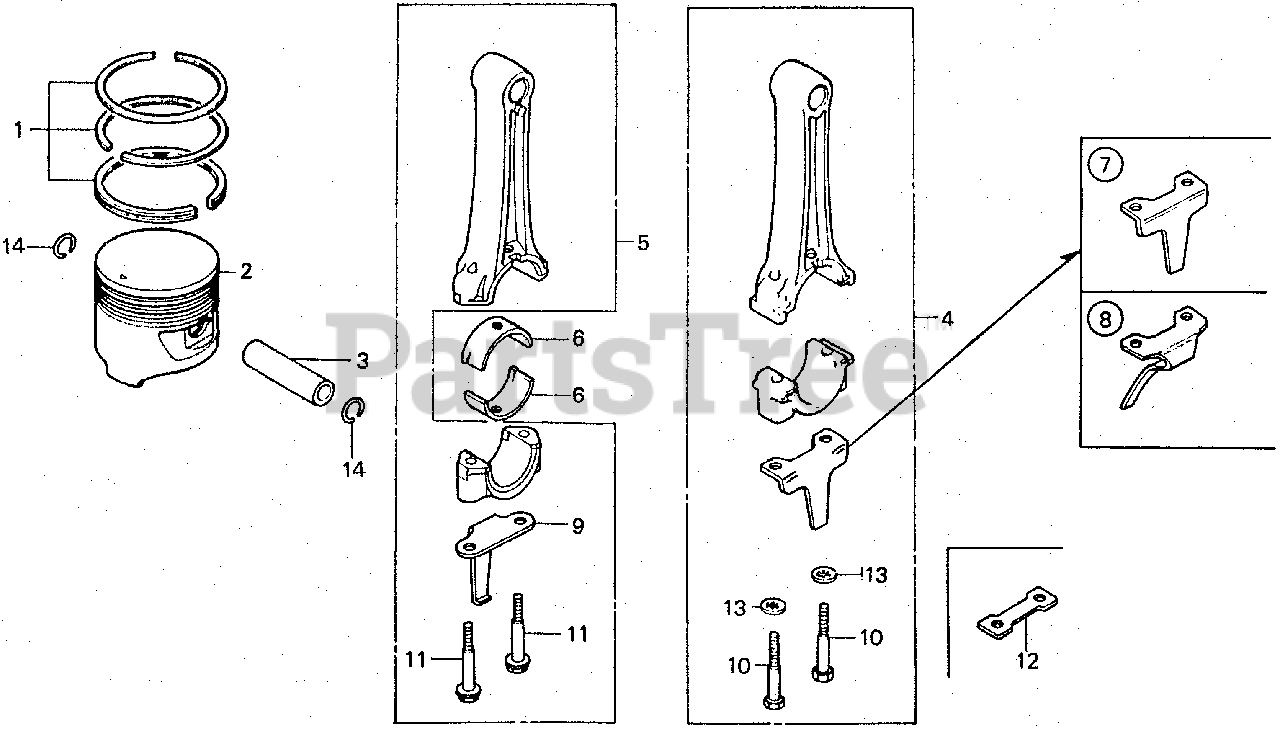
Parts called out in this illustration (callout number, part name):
1	RING SET, PISTON (STD)
1	RING SET, PISTON (STD) (NOT AVAILABLE)
1	RING SET, PISTON (OS 0.25)
1	RING, PISTON (OS 0.50)
1	RING SET, PISTON (OS 0.50)
1	RING SET, PISTON (0.75)
2	PISTON (STD)
2	PISTON (OS 0.25)
2	PISTON (OS 0.50)
2	PISTON (0.75)
3	PIN, PISTON
4	ROD ASSY., CONNECTING
4	ROD ASSY., CONNECTING (NOT AVAILABLE)
4	ROD ASSY., CONNECTING (US) Use up to Engine SN 1016894.
4	ROD ASSY., CONNECTING (US) Use from Engine SN 1016895 to 1041378.
4	ROD ASSY., CONNECTING (US) Use from Engine SN 1041379 to 1050927.
4	ROD ASSY., CONNECTING (US) Use from Engine SN 1050928 to 1086089.
5	ROD ASSY., CONNECTING
6	BEARING A, CONNECTING ROD Use from Engine SN 1086090.
6	BEARING B, CONNECTING ROD Use from Engine SN 1086090.
6	BEARING C, CONNECTING ROD Use from Engine SN 1086090.
6	BEARING D, CONNECTING ROD Use from Engine SN 1086090.
6	BEARING E, CONNECTING ROD Use from Engine SN 1086090.
7	DIPPER, CONNECTING ROD
7	DIPPER, CONNECTING ROD (NOT AVAILABLE)
8	DIPPER, CONNECTING ROD (NOT AVAILABLE)
9	DIPPER, CONNECTING ROD
10	BOLT, CONNECTING ROD (8MM) (NOT AVAILABLE)
11	BOLT, CONNECTING ROD (8MM)
12	WASHER, CONNECTING ROD
13	WASHER, LOCK (8MM)
14	CLIP, PISTON PIN (19MM)
